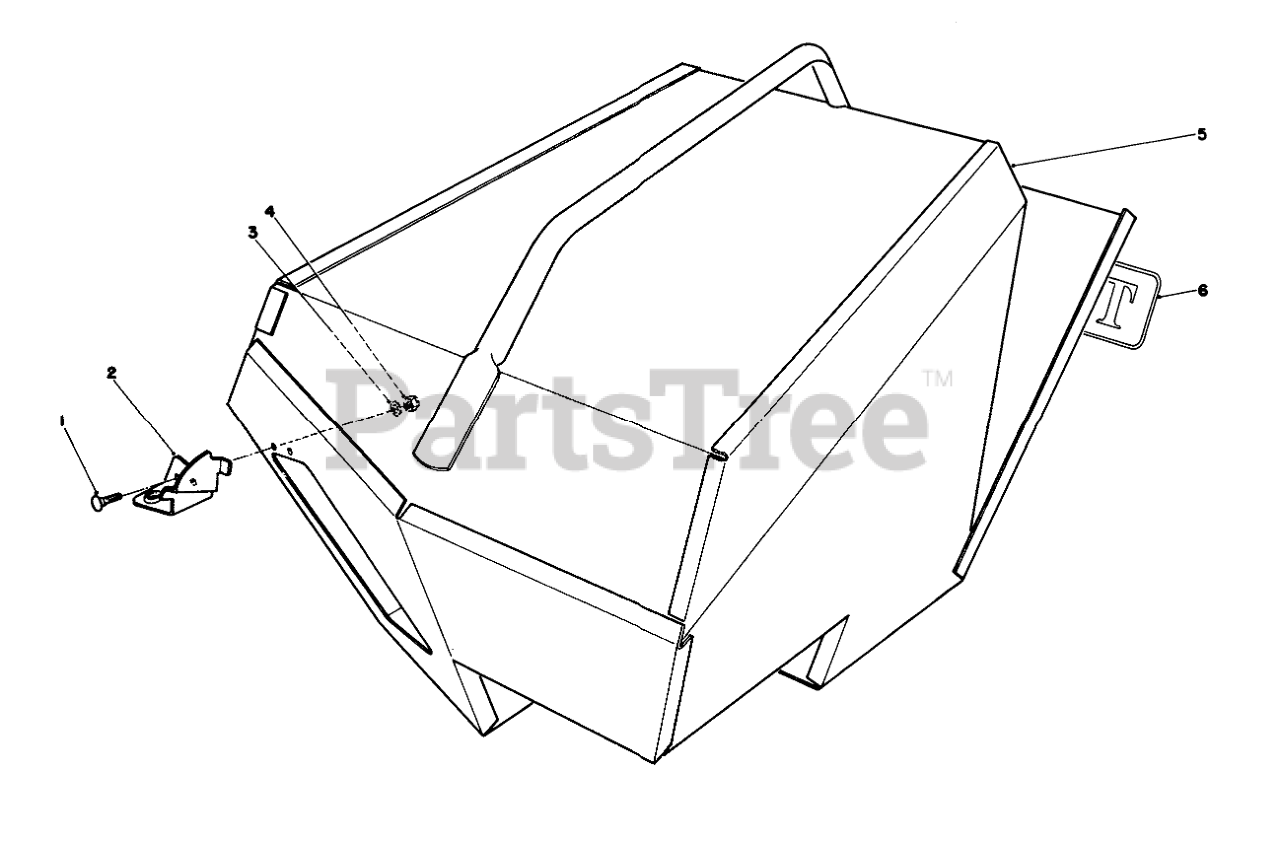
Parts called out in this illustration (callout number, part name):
1	SCREW-CARR
2	Bracket-Latch
3	WASHER-FLAT
4	NUT-LOCK, NI
5	Bag-Steel
6	Decal
